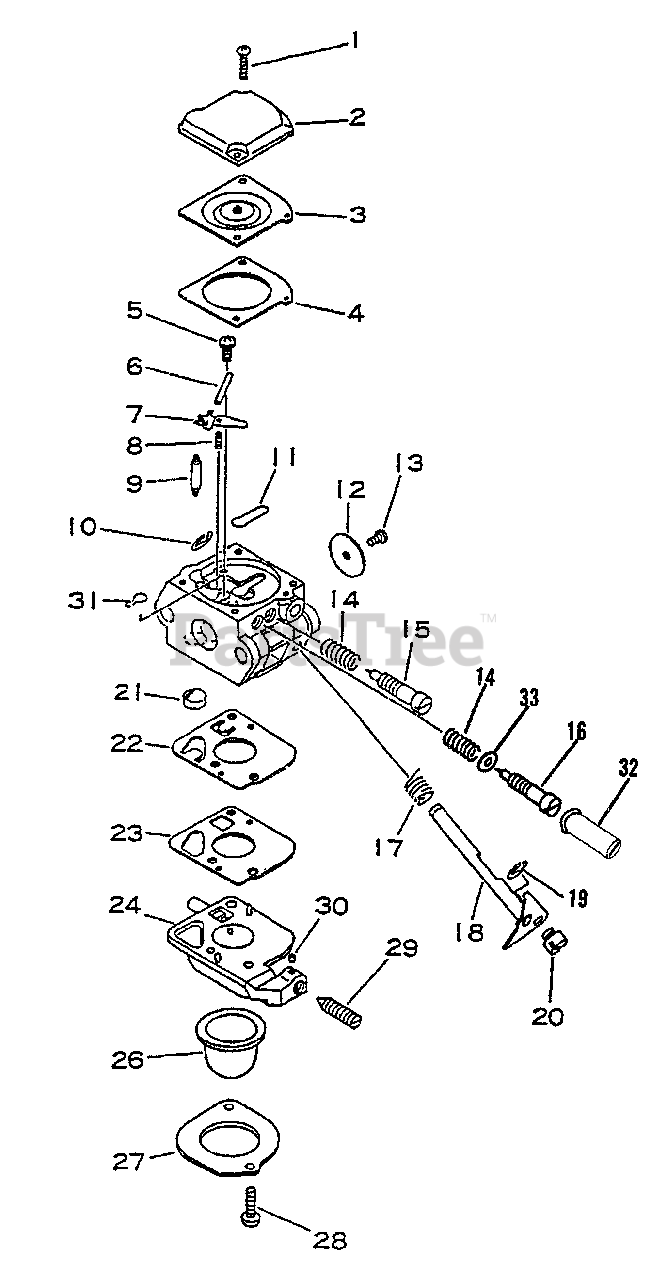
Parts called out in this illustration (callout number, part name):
2	COVER, METERING DIAPHRAGM
3	DIAPHRAGM
4	GASKET, DIAPHRAGM
6	PIN, METERING LEVER
7	LEVER, METERING
8	SPRING
9	VALVE, NEEDLE
11	PLUG, WELCH
12	VALVE, THROTTLE
14	SPRING, NEEDLE
15	NEEDLE, IDLE
16	NEEDLE, HIGH SPEED
17	SPRING, THROTTLE RETURN
18	SHAFT, THROTTLE
21	STRAINER
22	DIAPHRAGM, PUMP
23	GASKET, PUMP
24	BODY ASSY, PURGE
26	BULB, PURGE
27	RETAINER
29	SCREW, IDLE ADJUST
30	PIECE, FRICTION
31	PLUG, WELCH
32	CAP, LIMITER
